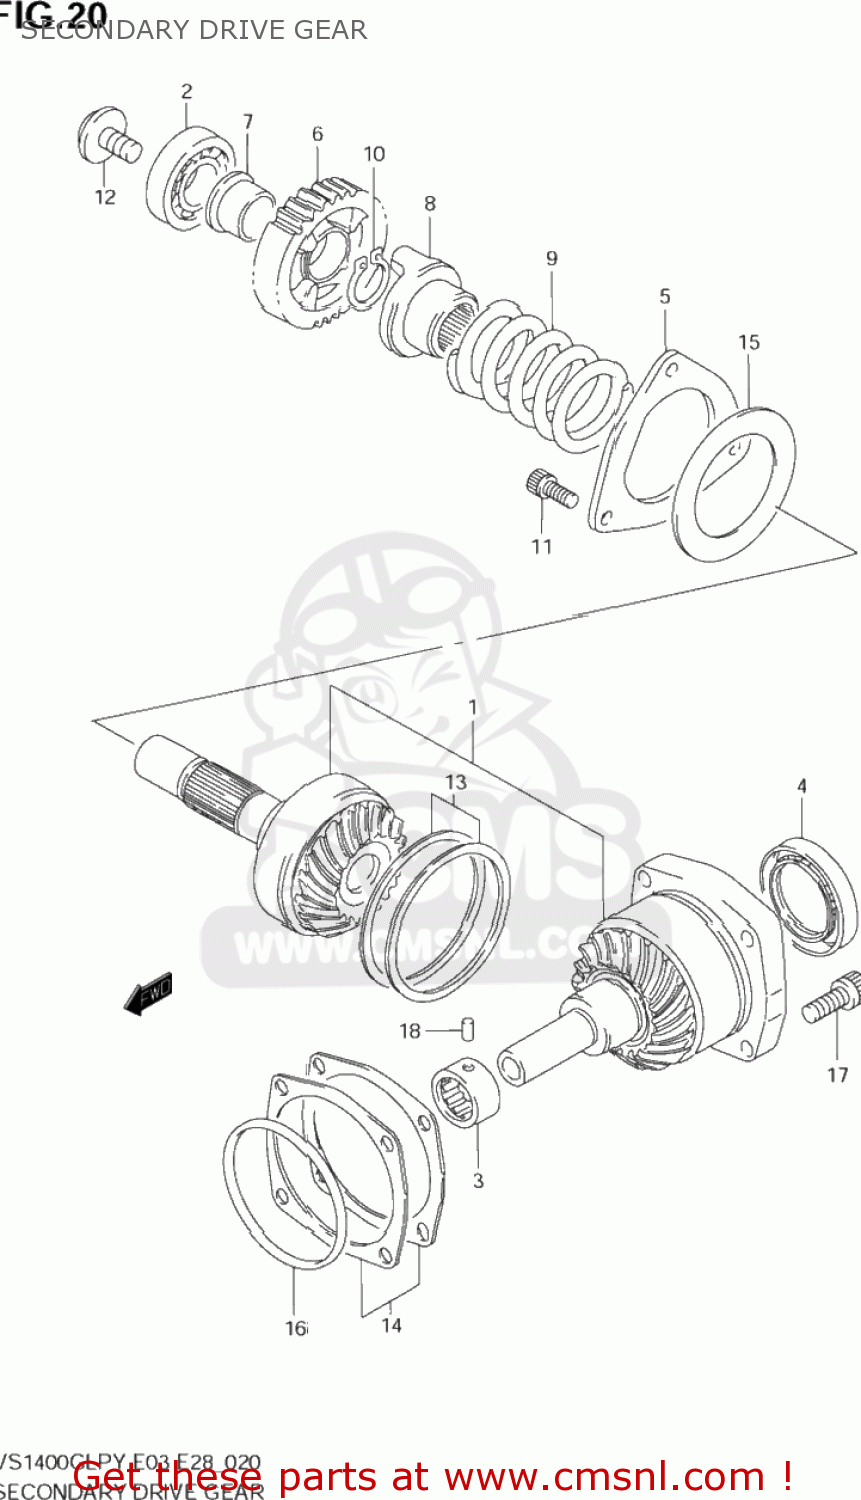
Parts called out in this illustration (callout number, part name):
1	GEAR & HOUSING SET,SECONDARY
2	BEARING(25X62X17)
3	BEARING(20X34X16)
4	SEAL,OIL(44X68X8)
5	STOPPER,SEC DRIVE BEARING
6	GEAR,OVER DRIVING DRIVEN
7	BUSHING,OD DRIVEN GEAR
8	DOG,OUTPUT CAM
9	SPRING
10	CIRCLIP
11	BOLT
12	BOLT(14X21)
13	SHIM SET,SEC DRIVE
14	SHIM SET,SEC DRIVEN
15	WASHER(57X90X3)
16	O RING(D:3.7,ID:76.5)
17	BOLT
18	PIN
